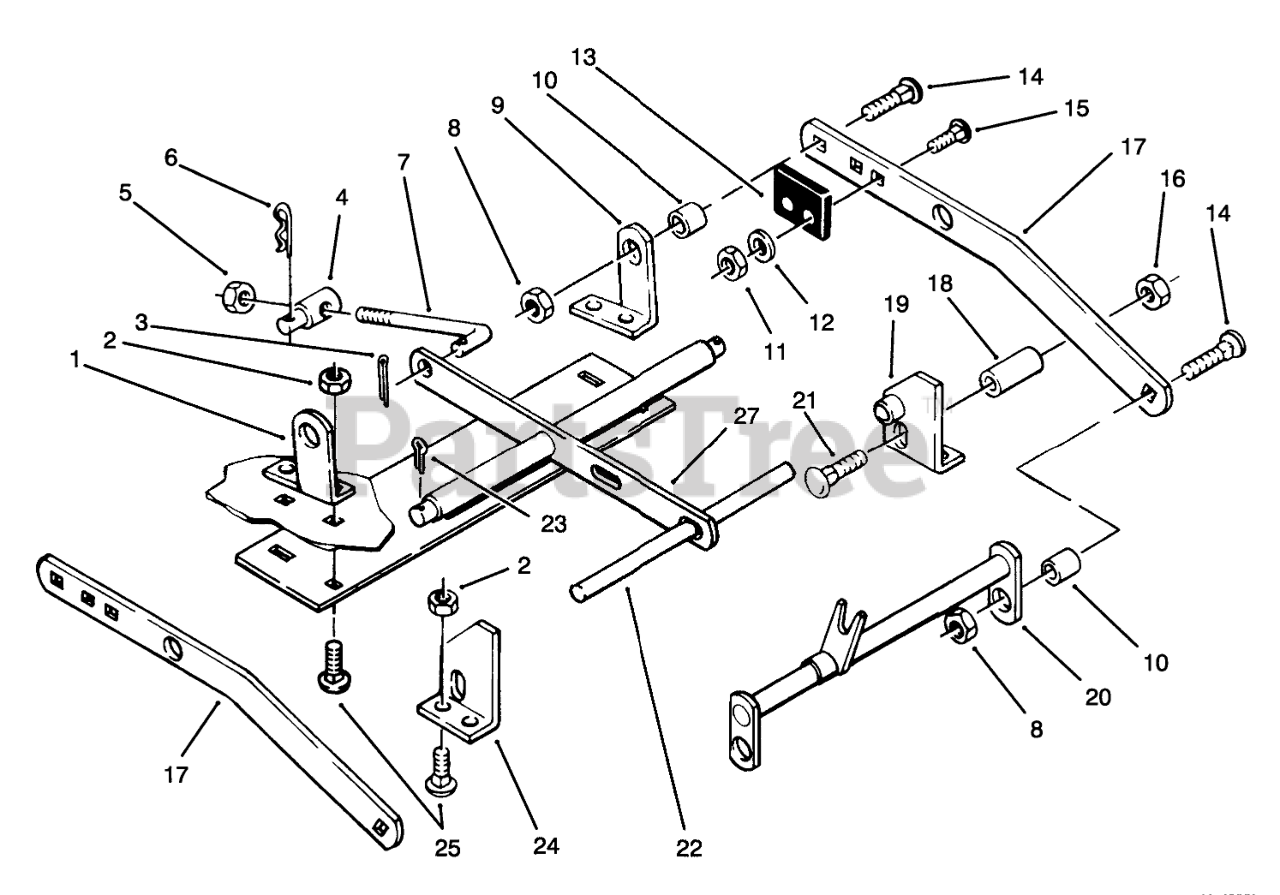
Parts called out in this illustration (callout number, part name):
1	Rear Bracket RH
2	NUT-LOCK, NI
3	PIN-COTTER
4	TRUNNION-LIFT
5	NUT-LOCK, NI
6	PIN-HAIR
7	ROD-LEVEL ADJUST
8	LOCKNUT-FLANGE
9	LH Rear Bracket
10	SPACER
11	NUT-LOCK, NI
12	WASHER-FLAT
13	BUMPER
14	BOLT-CARR
15	SCREW-CARR
17	Bar Draft
18	SPACER
19	Front Bracket LH
20	Hitch
21	BOLT-CARR
22	Front Shaft
23	PIN-COTTER
24	Front Bracket RH
25	BOLT-CARR
27	Leveler
